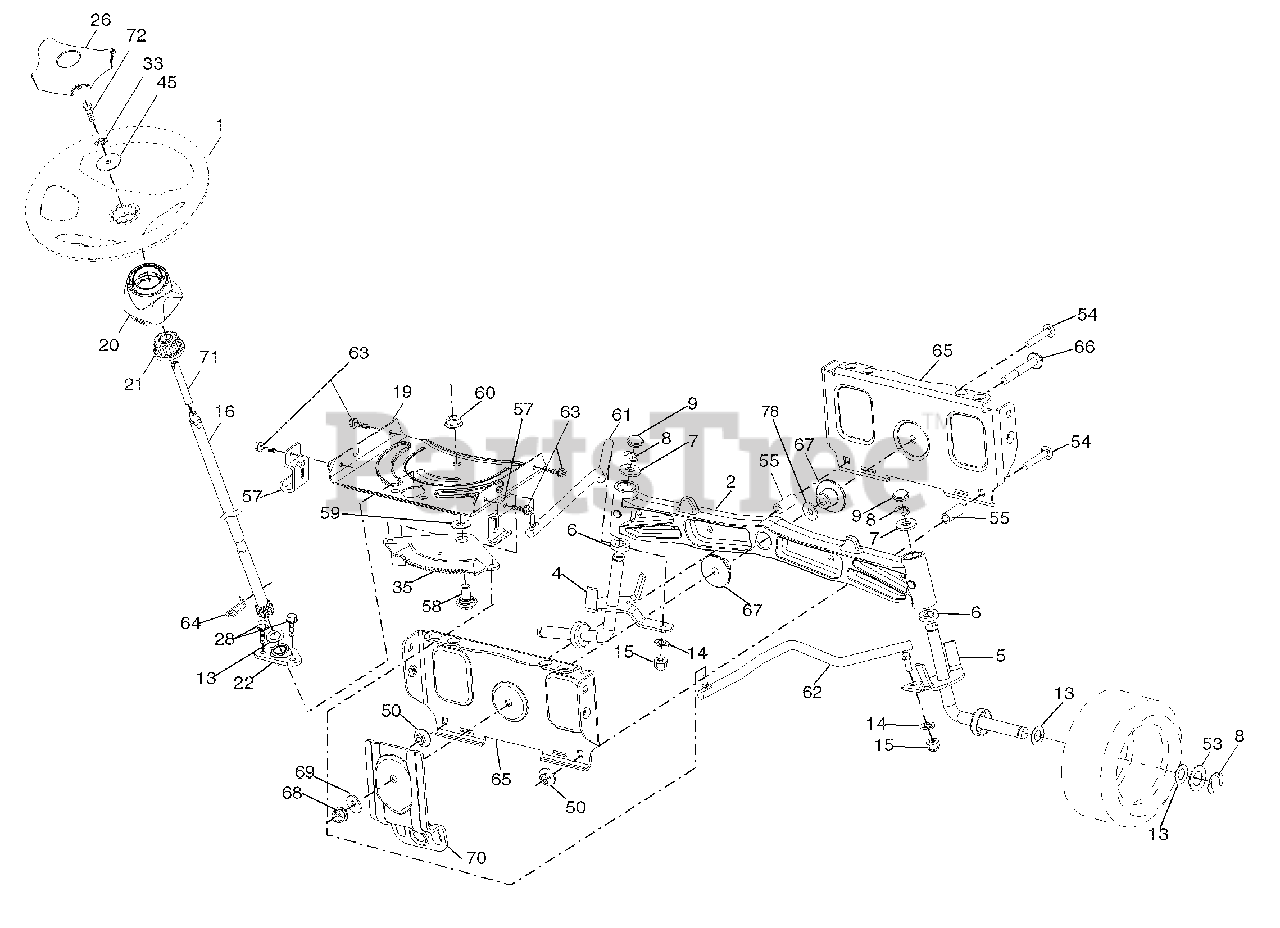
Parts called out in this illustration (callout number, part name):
1	Wheel, Steering
2	Axle Asm., Front
4	Spindle Asm., LH
5	Spindle Asm., RH
6	Bearing, Race Thrust Harden
7	Washer 25/32 x 1-5/8 x 16 Ga.
8	Ring, Clip #T5304-75
9	Cap, Spindle
13	Washer 25/32 x 1-1/4 x 16 Ga.
14	Washer Lock 3/8
15	Nut, Crown Lock 3/8-24 unf
16	Shaft Steering
19	Plate Steering
20	Boot, Steering
21	Adapter, Wheel Steering
22	Bushing, Strg. Blk
26	Insert, Wheel Steering
28	Screw 3/8-16 x 3/4
33	Washer Lock 5/16
35	Gear, Sector Plate
45	Washer 11/32 x 2-3/8 x 12 Ga.
50	Nut Lock Flg 3/8-16 unc
53	Washer Hardened .793 x 1.637 x .060
54	Bolt Hex HS 3/8-16 unc x 2-1/4
55	Spacer Brace Axle
57	Bracket Upstop
58	Bolt Shoulder Sector Pivot CFM
59	Washer Thrust Sector Steering
60	Nut Flange Lock 5/8-11
61	Draglink, LH
62	Draglink, RH
63	Screw 5/16-18 x 3/4
64	Retainer Clip Spring Steering
65	Brace Axle Front
66	Bolt Hex Fghd 7/16-14 x 3 Serr
67	Bushing PM Front Axle
68	Nut Lock Flange 7/16-14 Gr. 5
69	Washer 1.5 x .505 x .118
70	Bracket Deck Susp. Front
71	Shaft Ext. Steering
72	Bolt 5/16-18 x 4.5 Gr. 5
78	Washer Thrust .515 x .750 x .033
